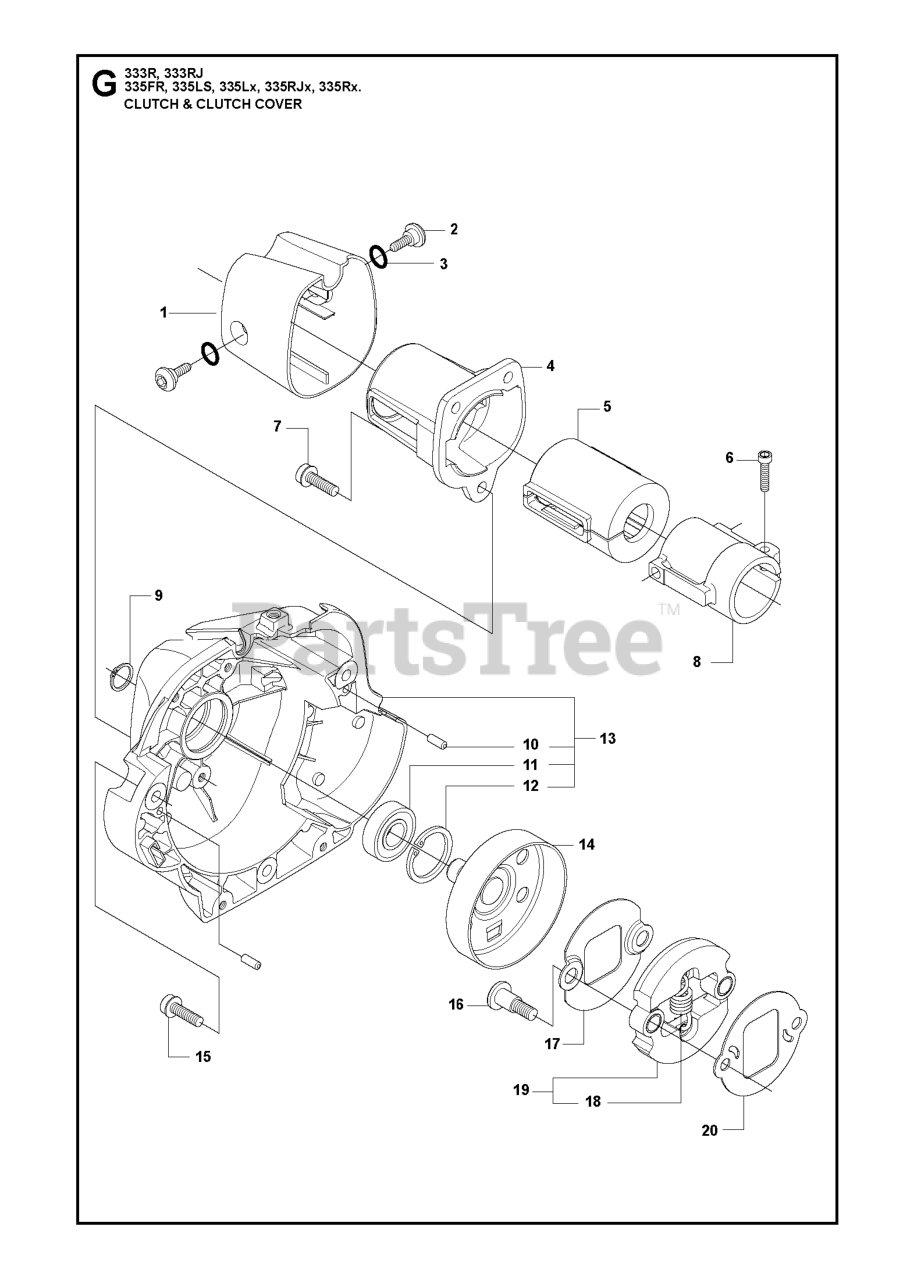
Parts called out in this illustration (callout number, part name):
1	COVER
2	SCREW MT5X11
3	O-RING 8X1.6
4	HOLDER, TUBE
5	VIBRATION ABSORBER
6	SCREW MC6S 5X25
8	SLEEVE, COVER
8	LOCKING SLEEVE
9	SEEGER CLIP
11	BALL BEARING
12	RETAINING RING SGH 28
13	CLUTCH COVER
14	CLUTCH DRUM
16	SCREW CLUTCH
19	CLUTCH CPL
20	WASHER
